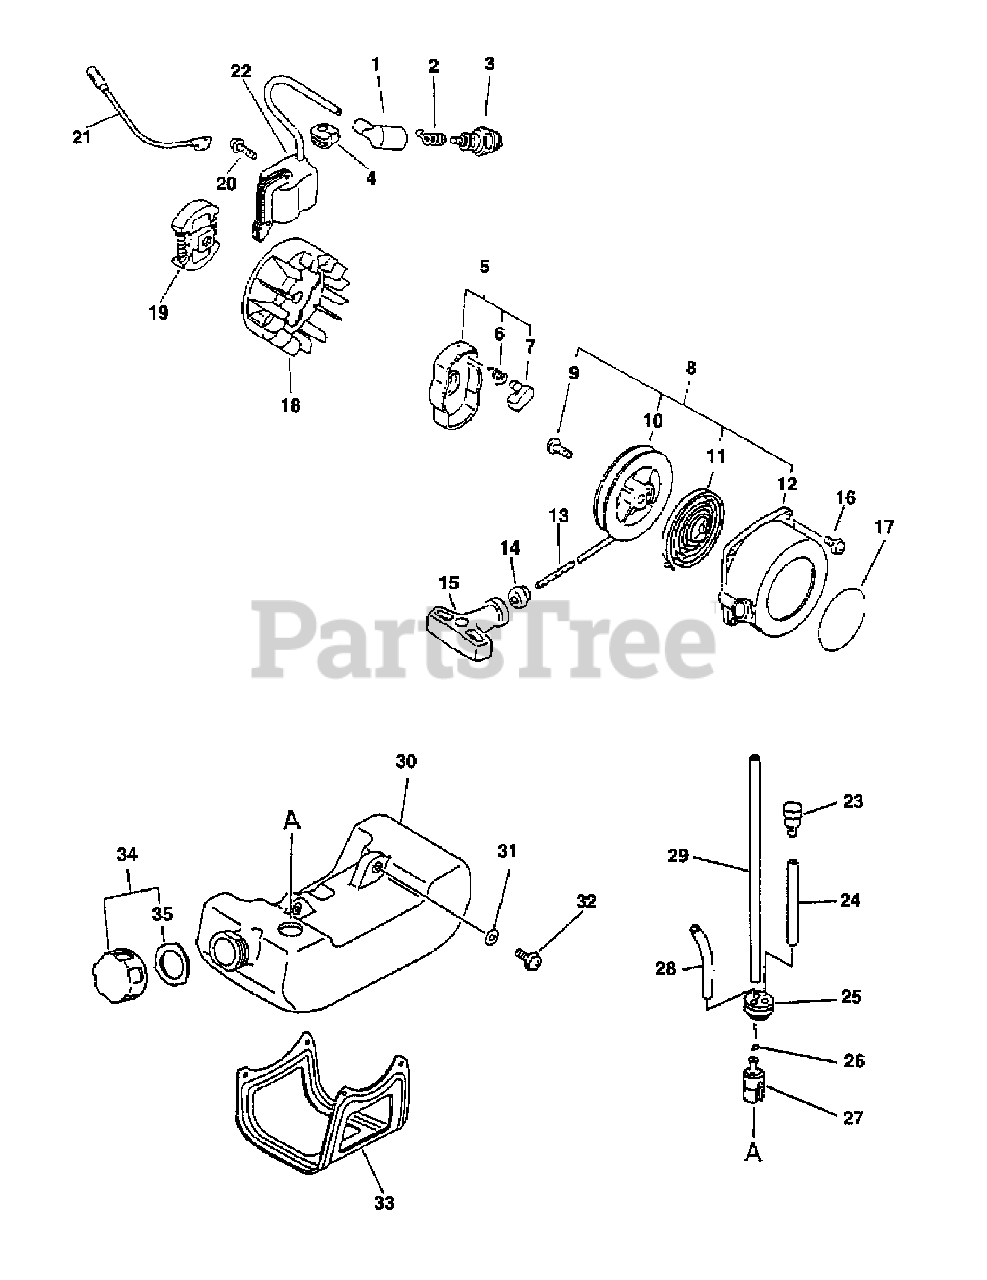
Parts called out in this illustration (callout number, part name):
1	CAP, SPARK PLUG
2	TERMINAL, SPARK PLUG CAP
3	SPARK PLUG -- BPM-7Y
3	SPARK PLUG -- BPMR-7A
5	STARTER PAWL ASSY
6	SPRING, RETURN
7	PAWL, STARTER - BLACK
8	STARTER ASSY
10	REEL, ROPE
11	SPRING, REWIND
12	CASE, STARTER
13	ROPE, STARTER - 3X1000
14	GUIDE, ROPE
15	GRIP, STARTER
16	SCREW - 4X16
17	LABEL - ECHO
18	FLYWHEEL
19	CLUTCH ASSY
20	SCREW - 4X22
21	LEAD - IGNITION
22	COIL, IGNITION
23	VENT, FUEL TANK
24	PIPE - 3X5X70 -- BLACK
25	GROMMET
26	CLIP - 6
27	FILTER, FUEL
28	PIPE - 3X6X90 -- CLEAR
29	PIPE - 3X5X180 -- BLACK
30	FUEL TANK ASSY
31	WASHER - 5
32	SCREW - 5X16
33	GUARD, FUEL TANK
34	CAP ASSY
35	GASKET, CAP
